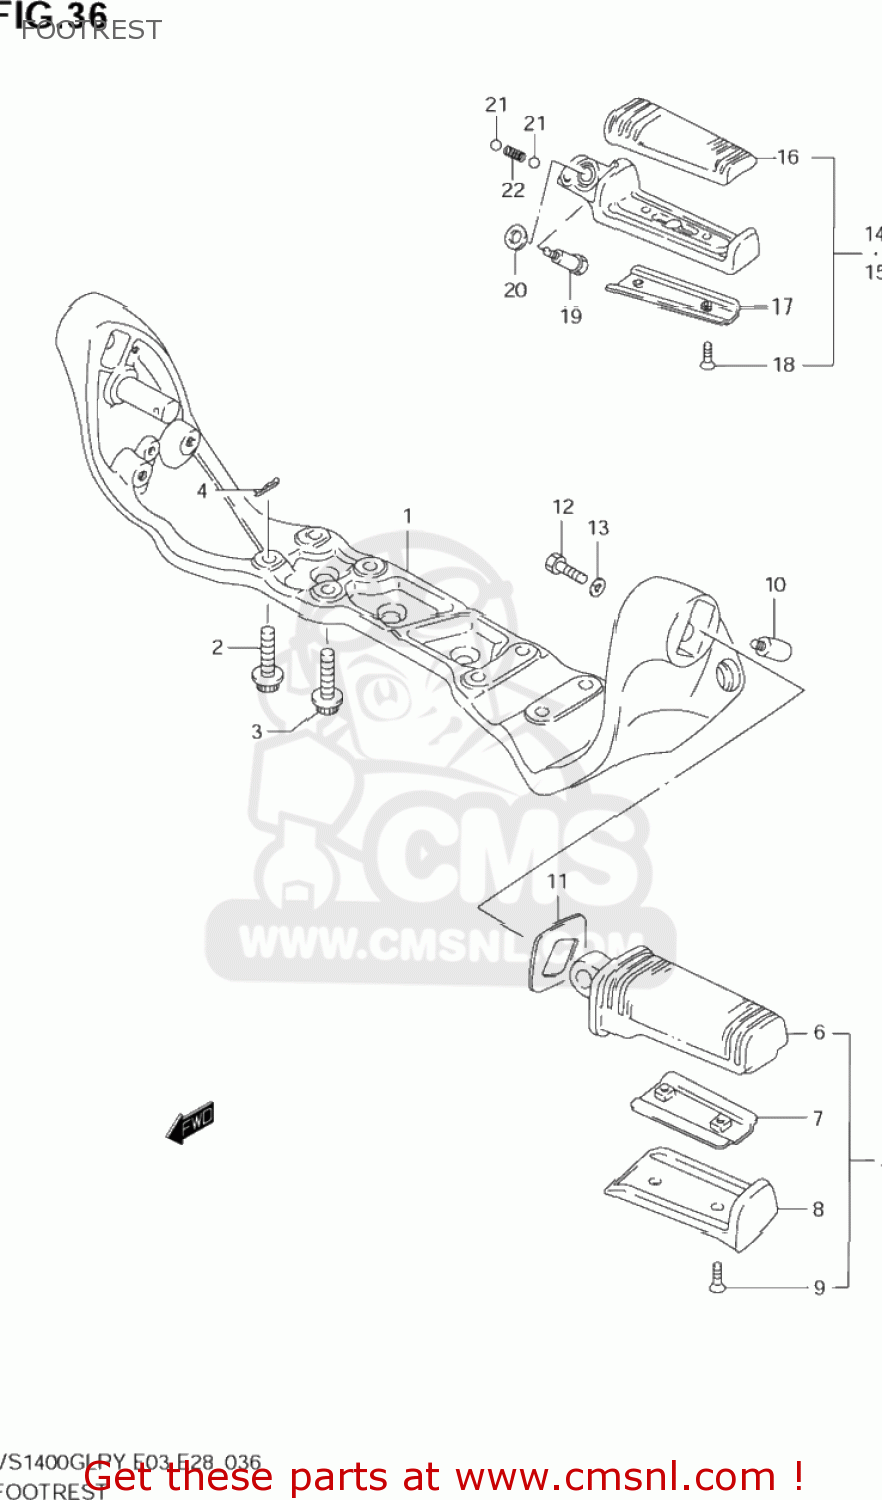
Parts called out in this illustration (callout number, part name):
1	BRACKET,FR FOOTREST
2	BOLT(8X25)
3	BOLT
4	SNAP
5	FOOTREST ASSY,FR,R
6	RUBBER,FR FOOTREST
7	PLATE,RUBBER STOPPER
8	COVER,FR FOOTREST
9	SCREW(5X20)
10	BOLT(6X8)
11	WASHER,FR FOOTREST
12	BOLT
13	LOCK,WASHER
14	FOOTREST ASSY RH
15	FOOTREST ASSY,PILLION,L
16	RUBBER,PILLION FOOTREST
17	PLATE,RUBBER STOPPER
18	SCREW(5X16)
19	BOLT(6X34.5)
20	SHIM
21	BALL
22	SPRING
